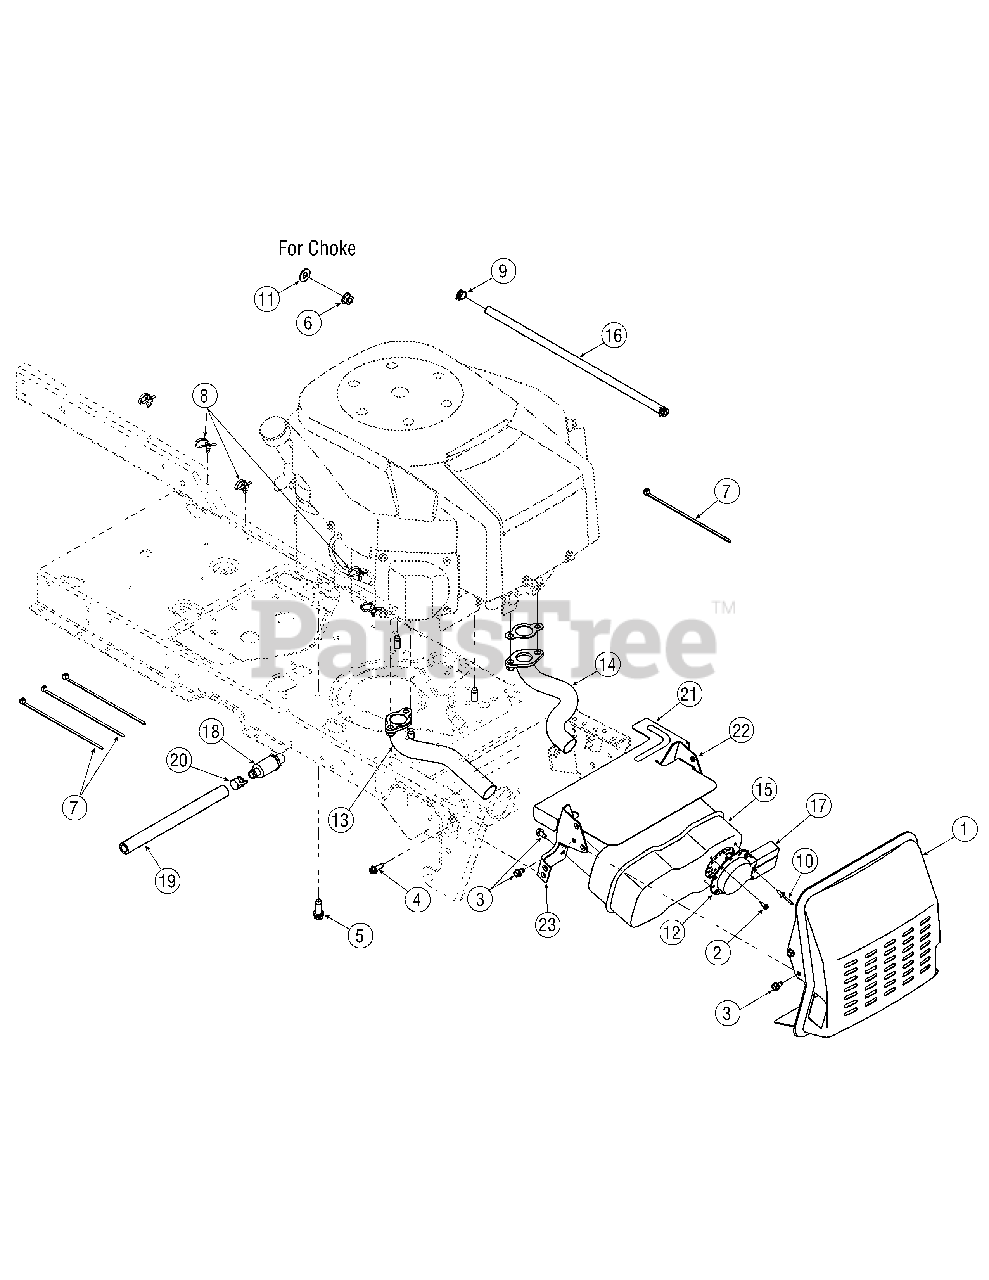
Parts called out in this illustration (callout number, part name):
2	Screw, Hex Wash Hd. Tapp, #8-18 x .5
3	Screw, Hex Wash Hd. Tapp, 1/4-20 x .5
4	Screw, Hex Wash Hd. Tapp, 1/4-20 x .75
5	Screw, Hex Sems Tapp, 3/8-16 x 1.0
6	Nut, Hex Flange Lock, 3/8-16 Gr5
7	Tie, Cable
8	Tie, Push Mount Cable
9	Clamp, Hose
10	Rivet, Pop, .188 x .3
11	Washer, Flat, .406 x .875 x .059
12	Deflector, Muffler
13	Pipe, Exhaust RH
14	Pipe Exhaust LH
15	Muffler, Dual Inlet
16	Hose, Fuel ; Low Permeation, 51 inches
17	Deflector, Muffler
18	Valve, Oil Drain
19	Hose, Oil Drain Extension
20	Cap, Drain Valve
21	Shield, Heat
